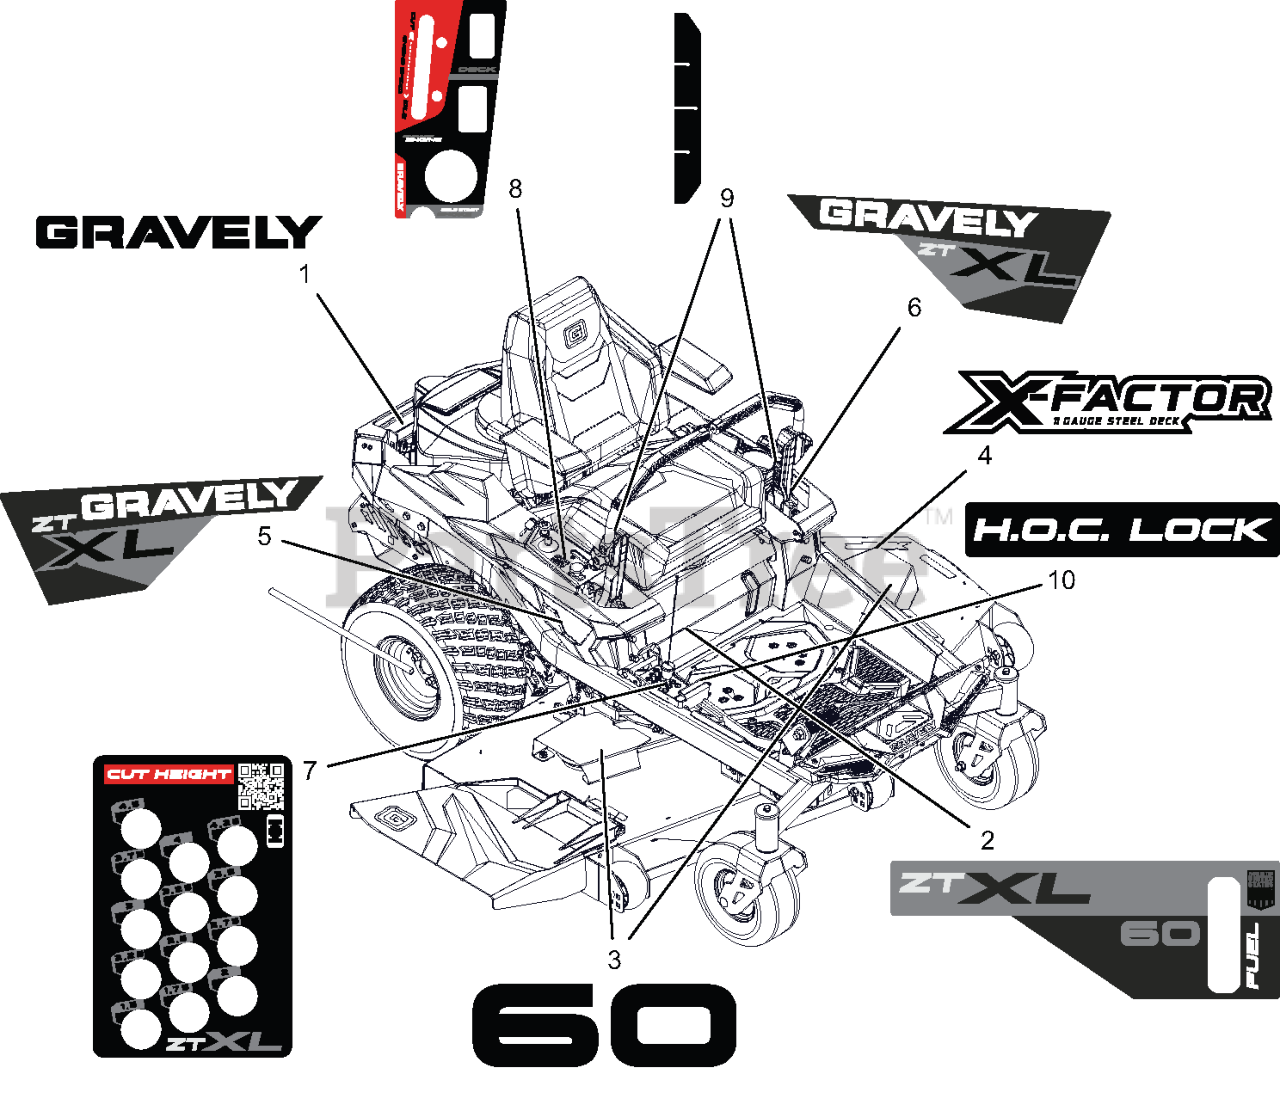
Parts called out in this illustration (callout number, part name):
1	DECAL- GRAVELY
2	DECAL- ZTXL 60-KICK PLATE
3	DECAL- DECK 60"
4	DECAL- DECK X-FACTOR
5	DECAL- ZT XL FENDER RH
6	DECAL- ZT XL FENDER LH
7	DECAL- HEIGHT OF CUT-XL
8	DECAL- CONTROL PANEL-GRAVELY
9	DECAL- HIRTH INDICATOR
10	DECAL- HOC LOCK
